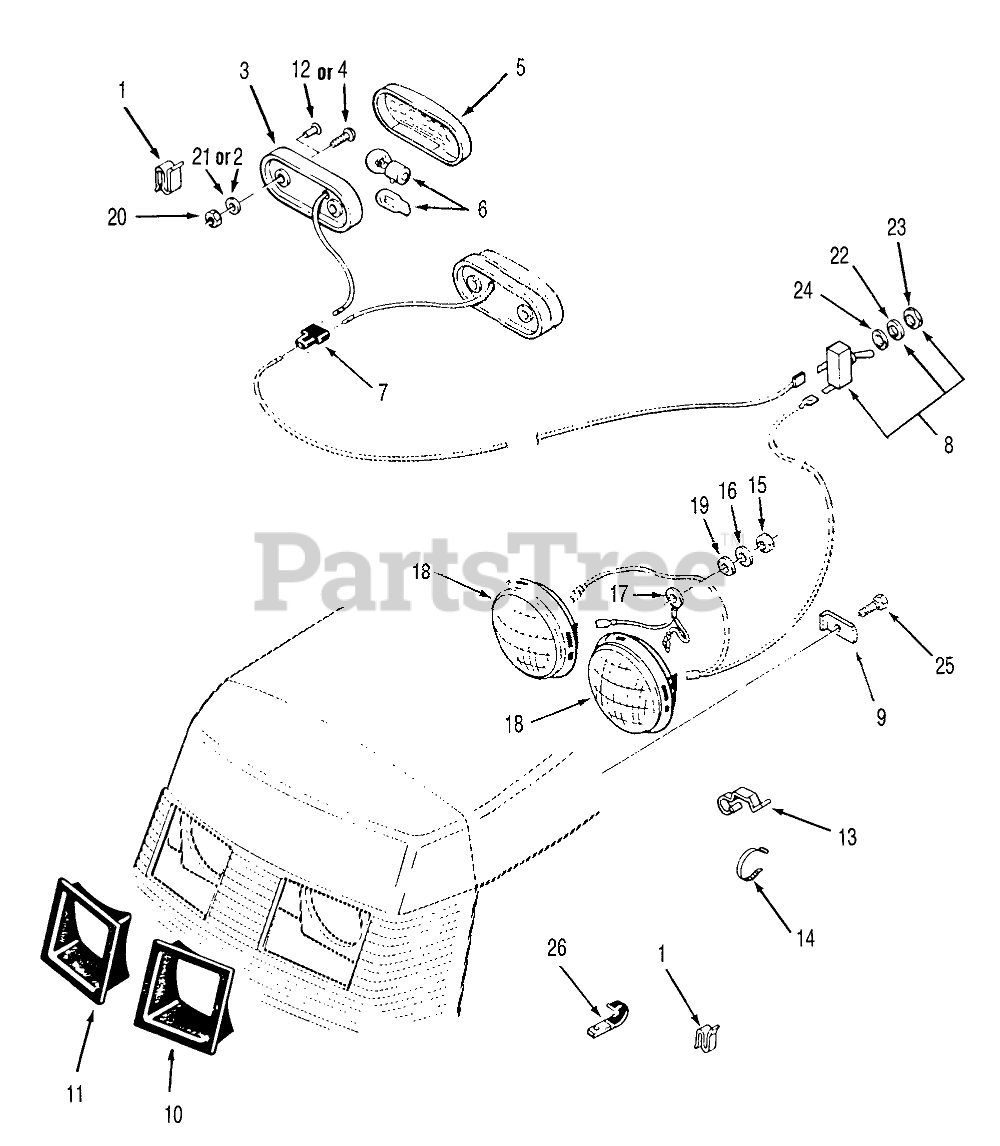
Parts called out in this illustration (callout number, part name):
1	SPEED CLIP
2	Lockwasher
3	BASE-TAIL LIGHT
4	Screw
5	LENS-TAIL LIGHT
6	Bulb
7	CONNECTOR 3 WIRE
8	SWITCH-LIGHTS
9	LOCK-HEADLIGHT
10	BEZEL-HEADLIGHT, LH
11	BEZEL-HEADLIGHT, RH
12	RIVET-4
13	CLIP-WIRE
14	PLASTIC TIE
15	Nut
16	Washer-Lock
17	LIGHT GROUND WIRE
18	HEADLAMP
19	WASHER 5/16 SAE
20	Nut
21	WASHER
22	TAB-WASHER
23	NUT-HEX
24	Washer
25	Bolt
26	CLIP
